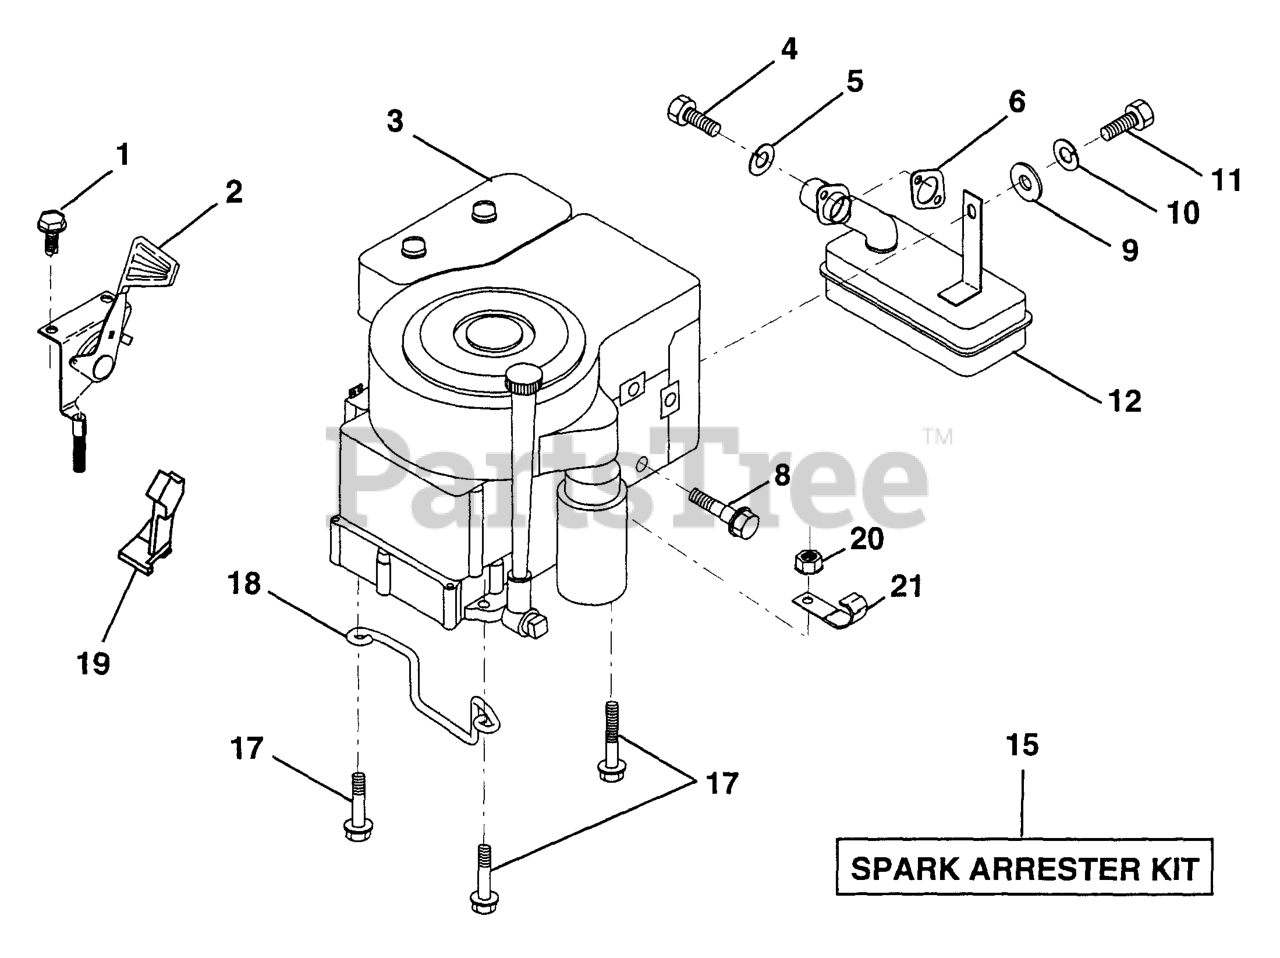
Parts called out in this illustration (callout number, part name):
1	SCREW
2	CONTROL.TH/CH.RH.BLK.FLG.26
3	Engine
4	SCREW
5	WASHER.LOCK.HVY.HLCL.SPR.5/16
6	GASKET ENGINE
9	WASHER
10	LOCKWASHER
11	Bolt Hex Fin
12	MUFFLER.SINGLE.B&S.12HP
15	KIT.SPARK ARRESTOR 794945 B&S
17	SCREW LT
18	KEEPER,DR BELT GR
19	STOP THROTTLE
21	CLIP T
